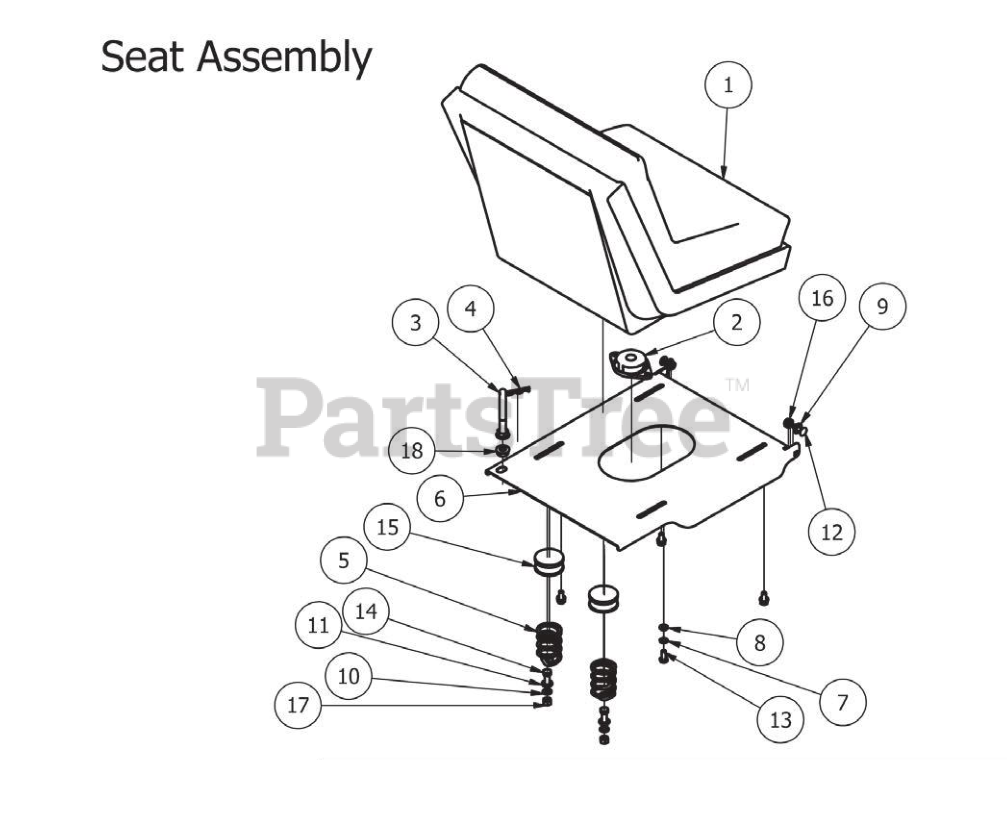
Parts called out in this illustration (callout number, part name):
1	Gray Bucket Seat with no Arms/Sides
2	Seat Safety Switch
3	Seat Bracket Pin
4	Seat latch pin
5	Seat Spring
6	MZ Seat Plate
7	5/16" Lock Washer
8	1/4" Flat Washer
9	.360 ID Plastic Washer
10	3/8" Lock Washer
11	3/8" Flat Washer
12	5/16-18 x 1 Carriage Bolts Zinc
13	5/16" x 3/4" Hex Bolt
14	3/8" x 1 1/4" Hex Bolt
15	Spring Cap Cover
16	5/16-18 Nylon Flange Nut
17	3/8" Hex Nut
18	1/2" Flange Nut
